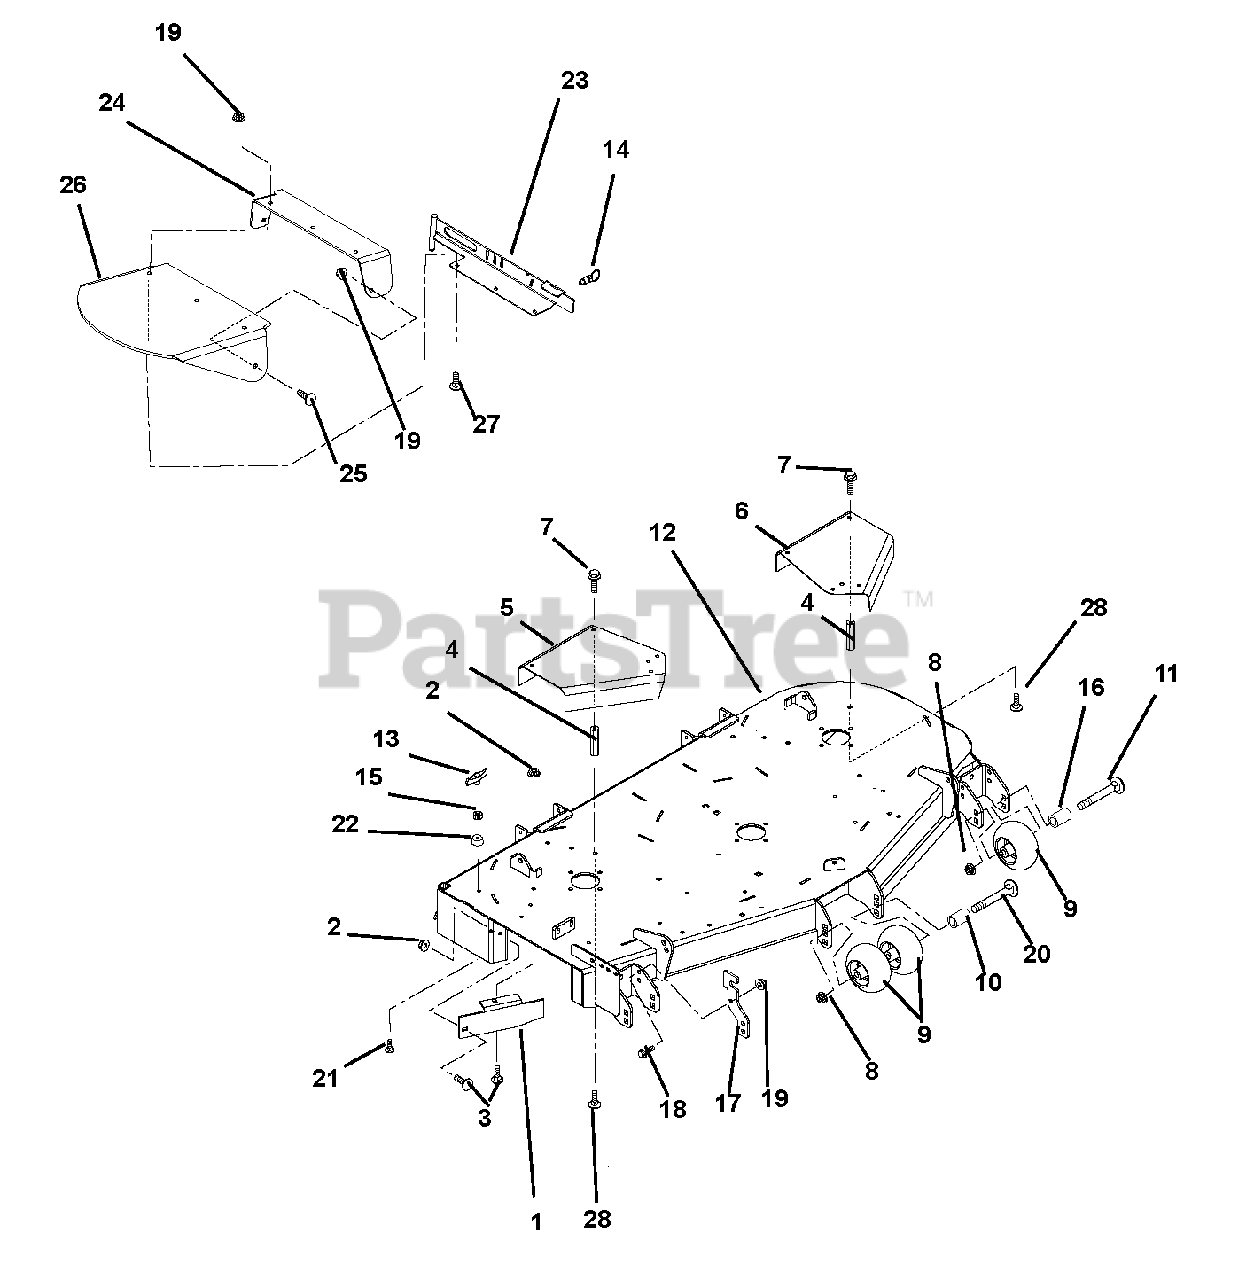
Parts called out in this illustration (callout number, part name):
1	60-in. Discharge Baffle (992156)
2	Nut, .31-18 Nyloc Flange
3	Bolt, Round Head Square Neck .31-18 x 1.00 Grade 5
4	Coupling Nut, .31-18 x 3.00
5	60-in. Right Hand Spindle Guard (992156)
6	60-in. Left Hand Spindle Guard (992156)
7	Bolt, SEMS .31-18 x .62
8	Nut .50-13 Nyloc Flange
9	Anti-Scalp Wheel
11	Bolt-Round Head Square Neck .50-13 x 5.00
12	60-in. Mower Deck (992156)
13	Knob, Wing .312-18
14	Pin, Pull Plunger .50-13 Thread x .310
15	Nut, Locking Center .31-18
16	Spacer, .510 x .625 x 3.35
17	Chute, Storage Bracket
18	Bolt, Hex .38-16 x 1.00
19	Nut, .38-16 Nyloc Flange
20	Bolt, Round Head Square Neck .50-13 x 8.50
21	Bolt, Round Head Square Neck .31-18 x 1.50
22	Bumper, Recessed 1.50 x .63 , .31 Thru Hole
23	60-inch Discharge Chute Mounting Weldment (992156)
24	Rubber Discharge Chute Support
25	Bolt, Round Head Square Neck .38-16 x 1.00 Grade 5
26	Chute, Rubber Discharge
27	Bolt, Round Head Square Neck .38-16 x 1.25 Grade 5
28	Bolt, Round Head Square Neck .31-18 x .75 Loc-Tite
